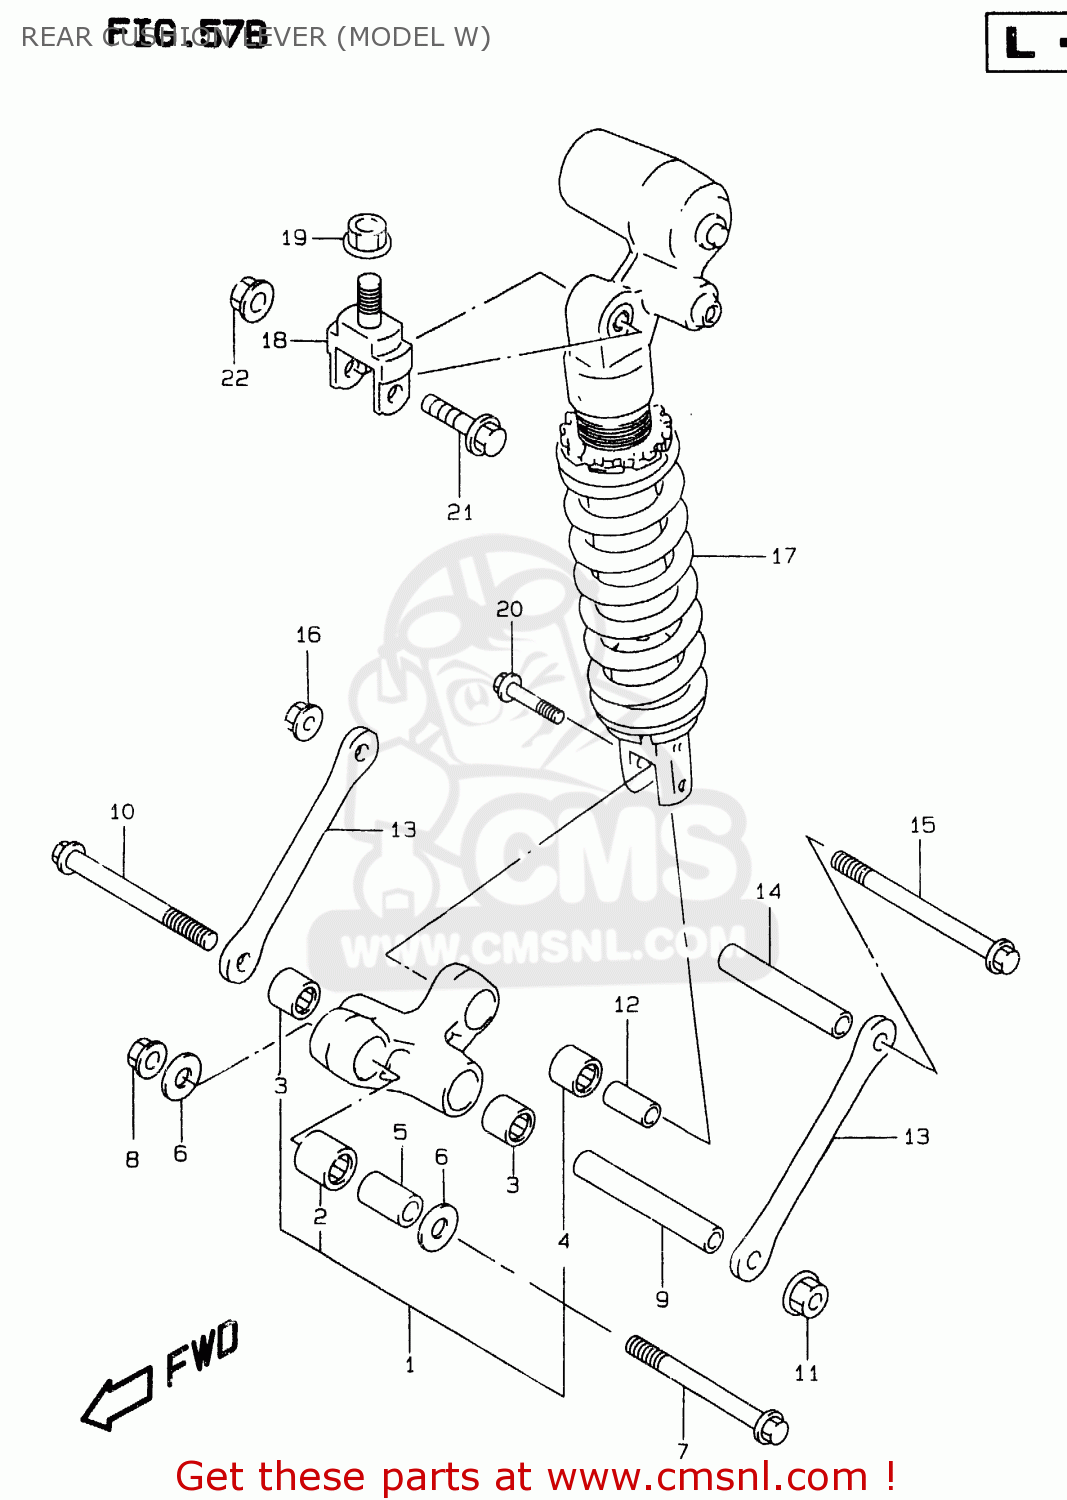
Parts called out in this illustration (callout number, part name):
1	LEVER SET,RR CUSHION
2	BEARING(20X27X30)
3	BEARING(17X24X20)
4	BEARING(17X24X26)
5	SPACER,RR CUSHION LEVER FR
6	WASHER
7	BOLT,RR CUSHION LEVER FR
8	NUT 12MM
9	SPACER,RR CUSHION LEVER CTR
10	BOLT,RR CUSHION LEVER CTR
11	NUT 12MM
12	SPACER,RR CUSHION LEVER
13	ROD,RR CUSHION LEVER
14	SPACER,RR CUSHION LEVER CTR
15	BOLT,RR CUSHION LEVER CTR
16	NUT 12MM
17	ABSORBER ASSEMBLY,REAR SHOCK
18	BRACKET,RR SHOCK ABSORBER UP
19	NUT
20	BOLT(10X44)
21	BOLT(10X54)
22	NUT
